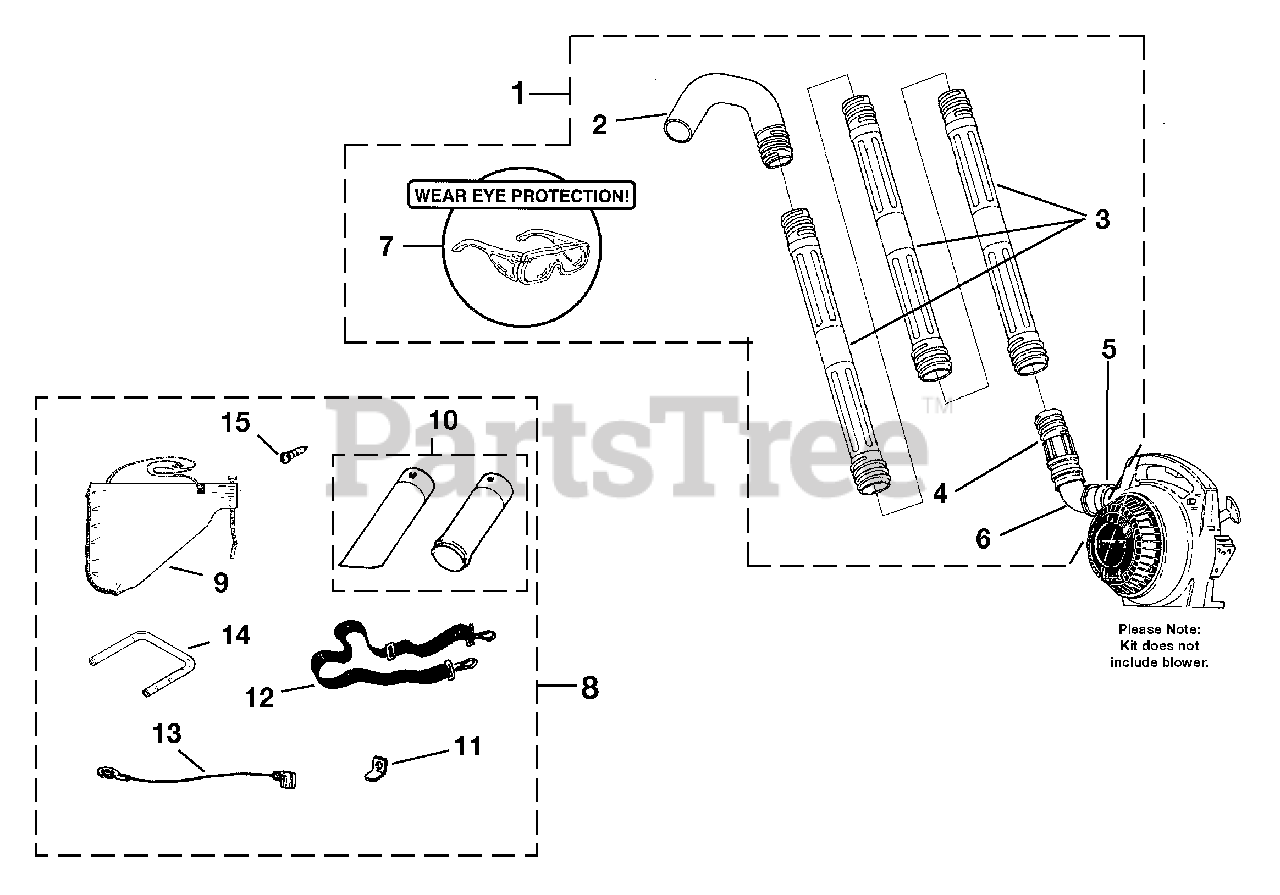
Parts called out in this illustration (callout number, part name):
1	GUTTER MAINTENANCE KIT
2	FULL ELBOW
3	STRAIGHT TUBE
4	ADAPTER GUTTER ATTACHMENT
5	CLAMP w/Fasteners
6	ADAPTER & ELBOW
7	SAFETY GLASSES-Clear
8	VACUUM KIT
9	LEAF BAG
10	VACUUM TUBE KIT w/ Decal
11	TAB-Male
12	HARNESS-Shoulder
13	LEAD-Ground
